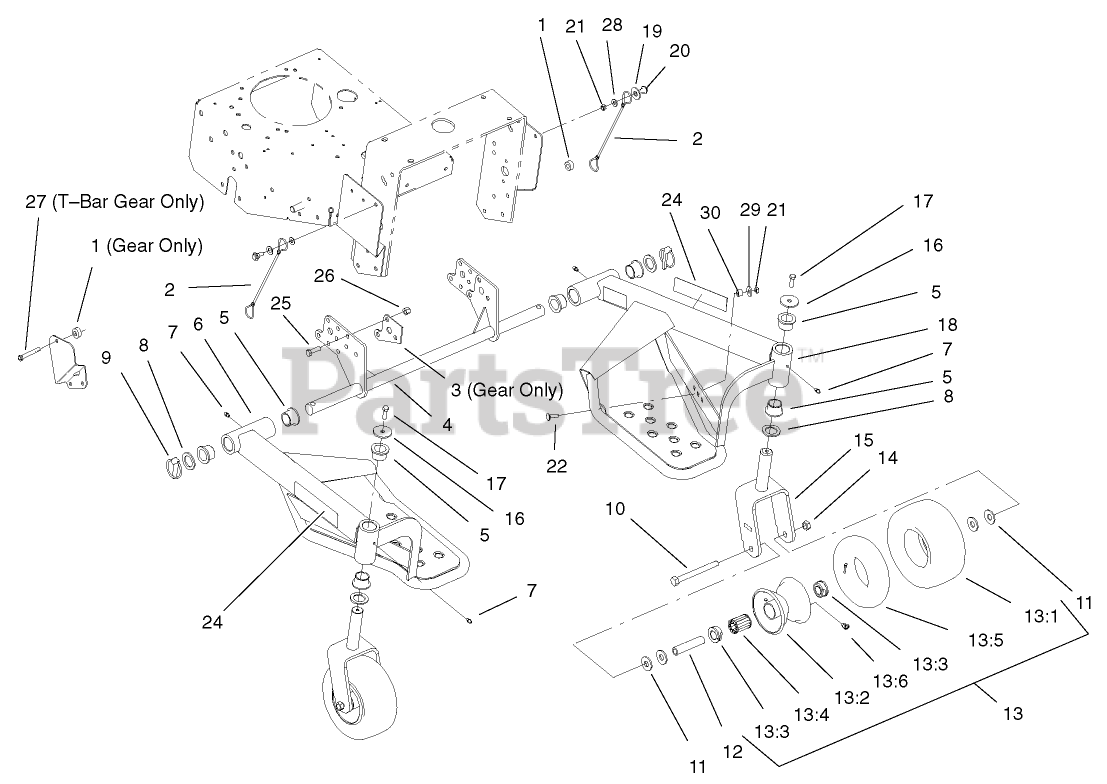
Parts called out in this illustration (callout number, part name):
1	SPACER
2	LANYARD
3	PLATE-SPACER
4	AXLE ASM
5	BUSHING
6	LH FLOOR PLATE ASM
7	FITTING-GREASE
8	WASHER-THRUST
9	PIN-LYNCH
10	SCREW-HH
11	WASHER-FLAT
12	SPANNER-TIRE
13	CASTOR WHEEL ASM
13:2	RIM ASM
13:3	BEARING-OUTSIDE
13:4	BEARING-ROLLER
13:6	FITTING-LUBE, 45 DEG
14	NUT-HEX
15	CASTOR ASM
16	WASHER-REBOUND
17	SCREW-HH
18	RH FLOOR PLATE ASM
19	WASHER-FLAT
20	BOLT-SHOULDER
21	NUT-LOCK, NI
22	BOLT-CARR
25	SCREW-HH
26	NUT-LOCK, NI
27	SCREW-HH
28	WASHER-FLAT
29	Washer-Friction
30	SPACER
